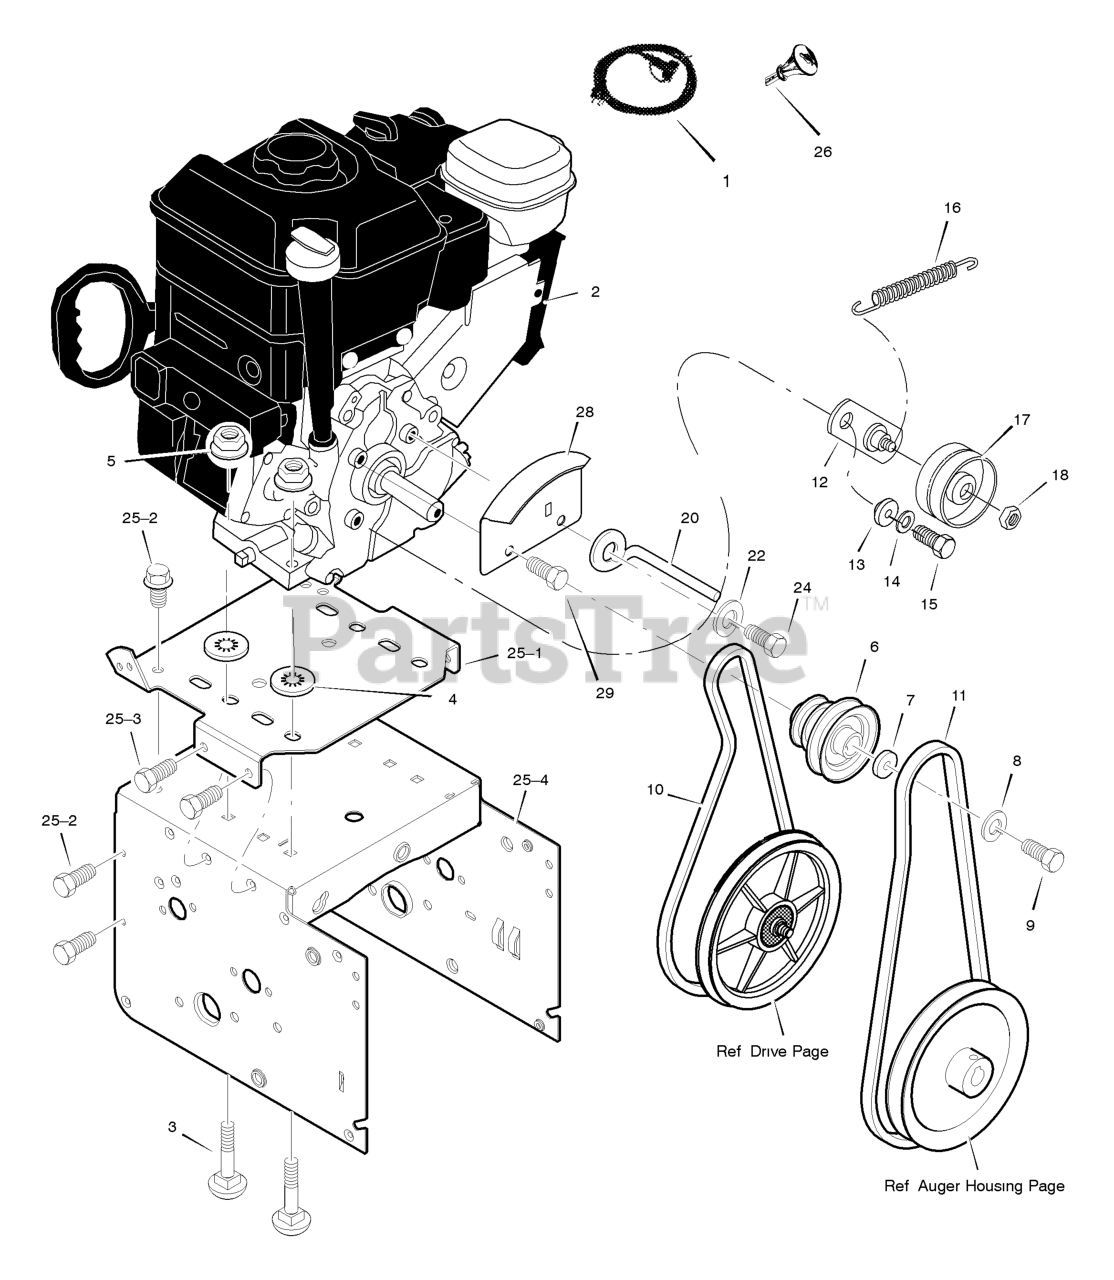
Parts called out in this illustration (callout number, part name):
1	CORD, Electric, 10FT. 110V
2	ENGINE
3	BOLT, CARRIAGE 5/16-18
4	RETAINER, PUSH
5	NUT 5/16-18
6	PULLEY, ENGINE
7	WASHER
8	WASHER
9	SCREW, 3/8-24 x 1.00
10	BELT, V 3L
11	BELT, V 4L
12	BRACKET ASSEMBLY, IDLER
13	BUSHING, IDLER BRACKET
14	WASHER
15	SCREW 5/16-24 X 0.75
17	PULLEY, IDLER
18	NUT, JAM 3/8-16
20	GUIDE, ROD BELT
22	WASHER, SPTLK .31X.58X.08
24	SCREW, 5/16-24 x 0.75
25	FRAME ASSEMBLY
25-1	PLATE, ENGINE MOUNT
25-2	SCREW 1/4-20 X .63
25-3	SCREW 5/16-18 X .50
25-4	FRAME, MOTOR BOX
26	KEY, IGNITION
28	BRACKET, ENGINE SHIELD
